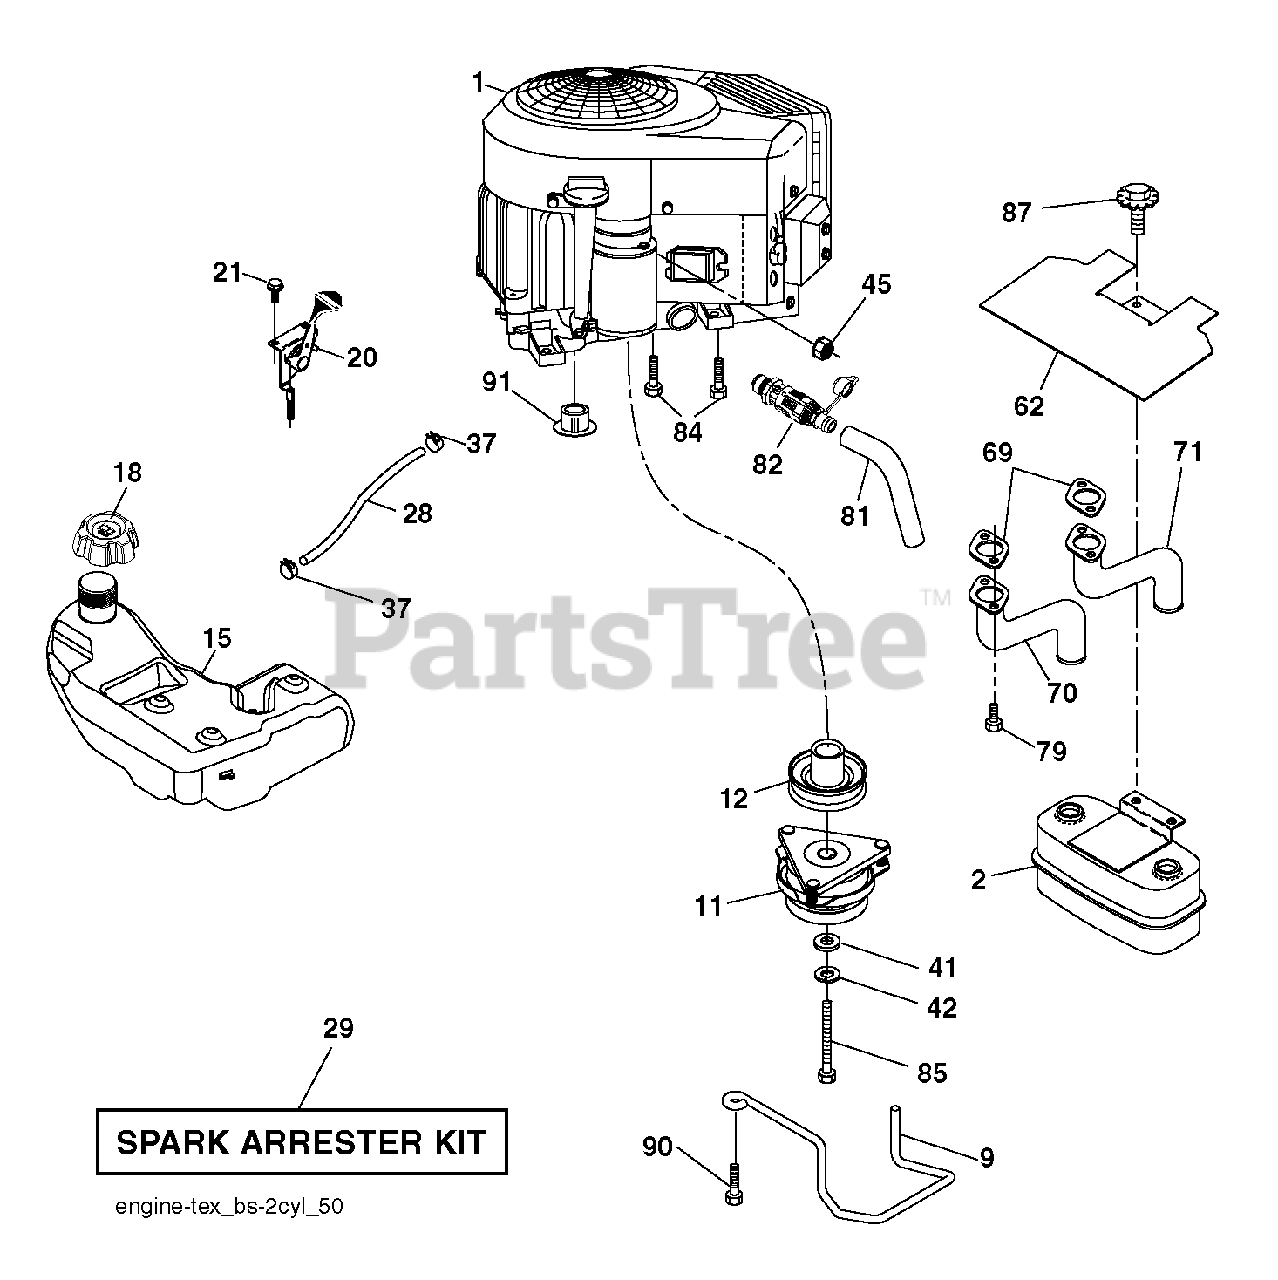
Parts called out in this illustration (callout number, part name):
1	Husqvarna TBD
2	MUFFLER.TWIN.CYL.LOW.TONE
9	KEEPER.BELT.ENGINE.4.2
11	CLUTCH.ELECTRIC.LT.48"*
12	PULLEY.ENGINE.TUFFTORQ
15	TANK.ASM.FUEL.3GA.CARB
18	CAP.ASM.FL.RITCH.3"E10.SYM.498
20	CONTROL.TH/CK.COBRA.B&S.TWN.
21	SCREW.#10 X 0.750.BOS
28	LINE.FUEL.64"REAR.EMIS
29	KIT.SPARK ARRESTOR 794945 B&S
37	HOSE CLAMP
42	LOCKWASHER
45	NUT
62	SHIELD.HEAT.MUFFLER
69	GASKET.MUFFLER
70	RP.EXHAUST.TUBE.LH.BS/TWIN
71	EXHAUST.TUBE.RH.BS/TWIN
79	SCREW.SOCKET.HEAD.5/16-18
81	TUBE, DRAIN OIL ASM.
82	VALUE.OIL.DRAIN
84	SCREW.3/8-16
85	BOLT HEX 7/16-20X4-1/4"
87	BOLT, 5/16-18 X 1 3/4
90	SCREW 3/8-16X1
91	BUSHING.1.375OD
109	CANNISTER, CARBON
110	VALVE.ASM.ANTI-SLOSH
111	RP PURGE LINE
113	VALVE.SLANT.CARTRDG.90 DEG.TEX
